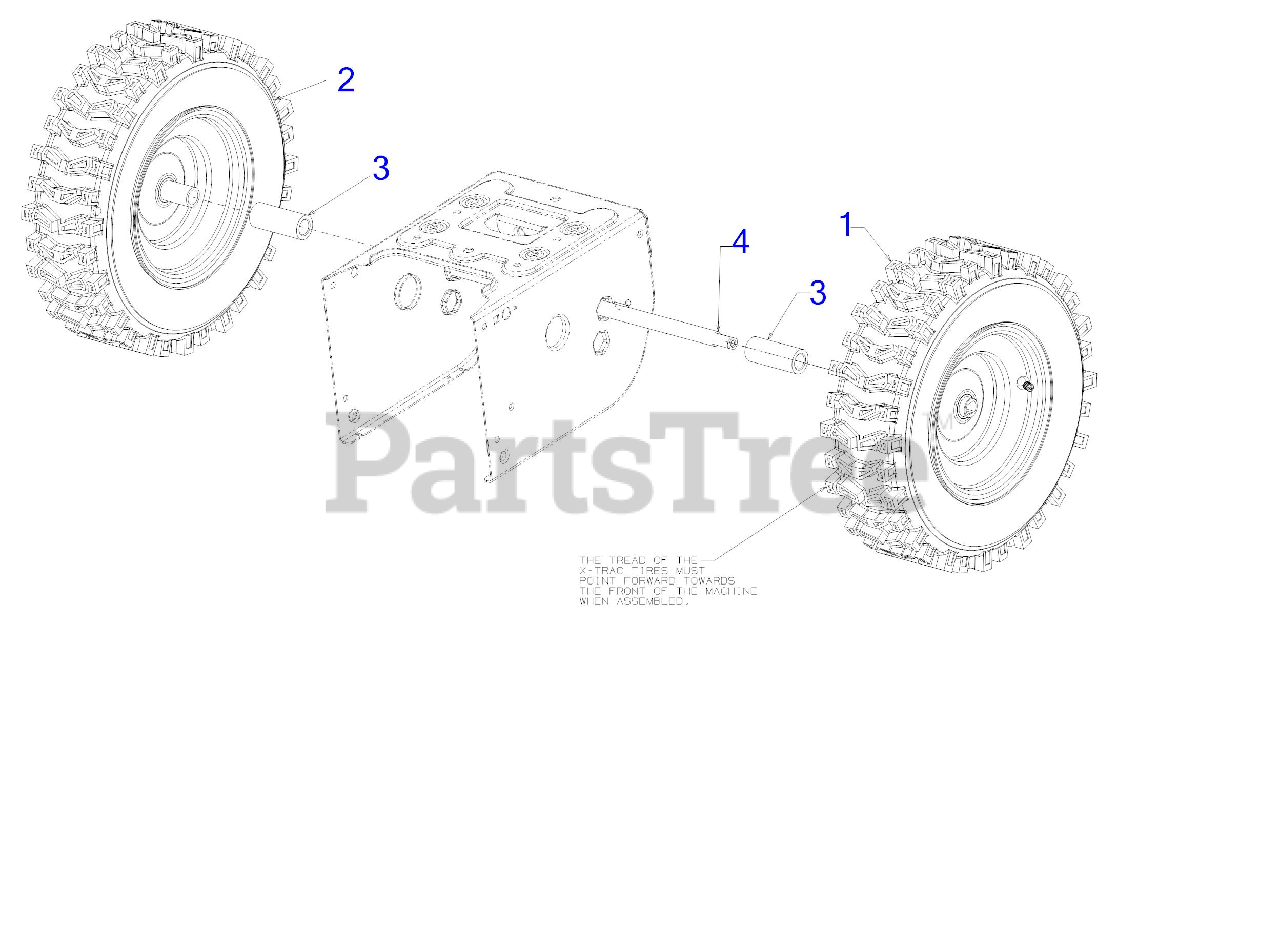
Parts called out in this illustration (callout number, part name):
1	WHEEL ASSEMBLY (16 x 4.8 x 8) (LH)
2	WHEEL ASSEMBLY (16 x 4.8 x 8) (RH)
3	WHEEL SPACER 1.25ODX.75X3.00
4	WHEEL AXLE SHAFT .75 x 22"
